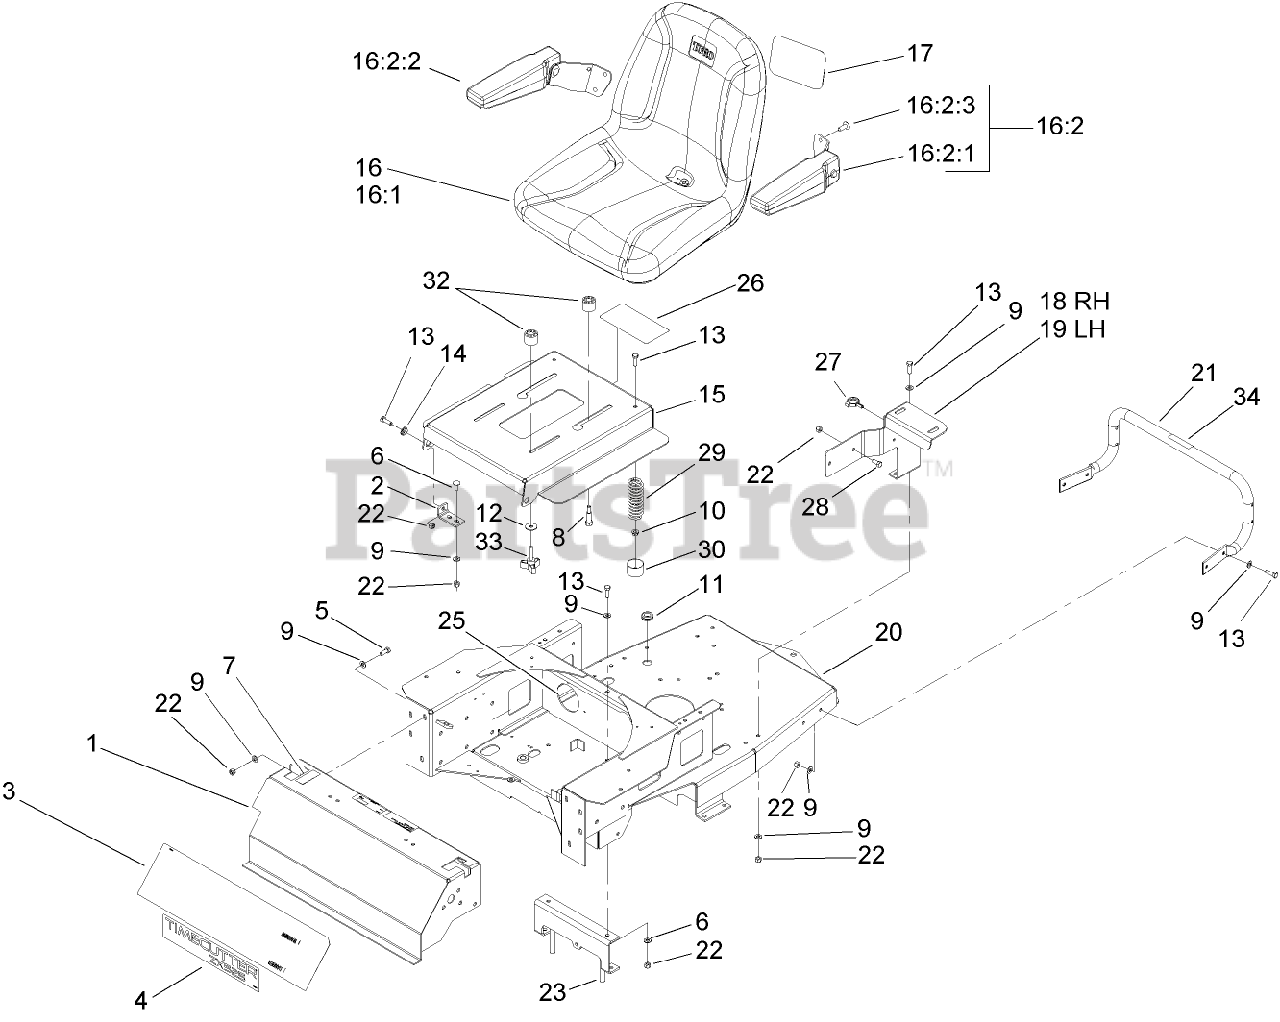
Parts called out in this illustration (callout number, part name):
2	BRACKET-PIVOT
3	DECAL-DANGER
5	SCREW-HH
6	SCREW-CARR
8	SCREW-SHOULDER, HH
9	WASHER-PLAIN
10	NUT-HF
11	GROMMET
12	WASHER-PIVOT
13	SCREW-HH
14	BUSHING
15	SEAT PAN ASM
16	SEAT (WITH ARM RESTS)
16:1	SEAT
16:2	Loose Parts Package
16:2:3	SCREW-HSBH
17	DECAL
18	BRACKET-RH
19	BRACKET-LH
20	REAR FRAME ASM
21	ROD-SUPPORT, REAR
22	NUT-LOCK, NI
25	COVER-CONDUIT
26	DECAL-SERVICE
27	CLAMP-HOSE
28	SCREW-HH
29	SPRING-COMPRESSION
30	CAP-PROTECTOR
32	SPACER
34	DECAL-WARNING
